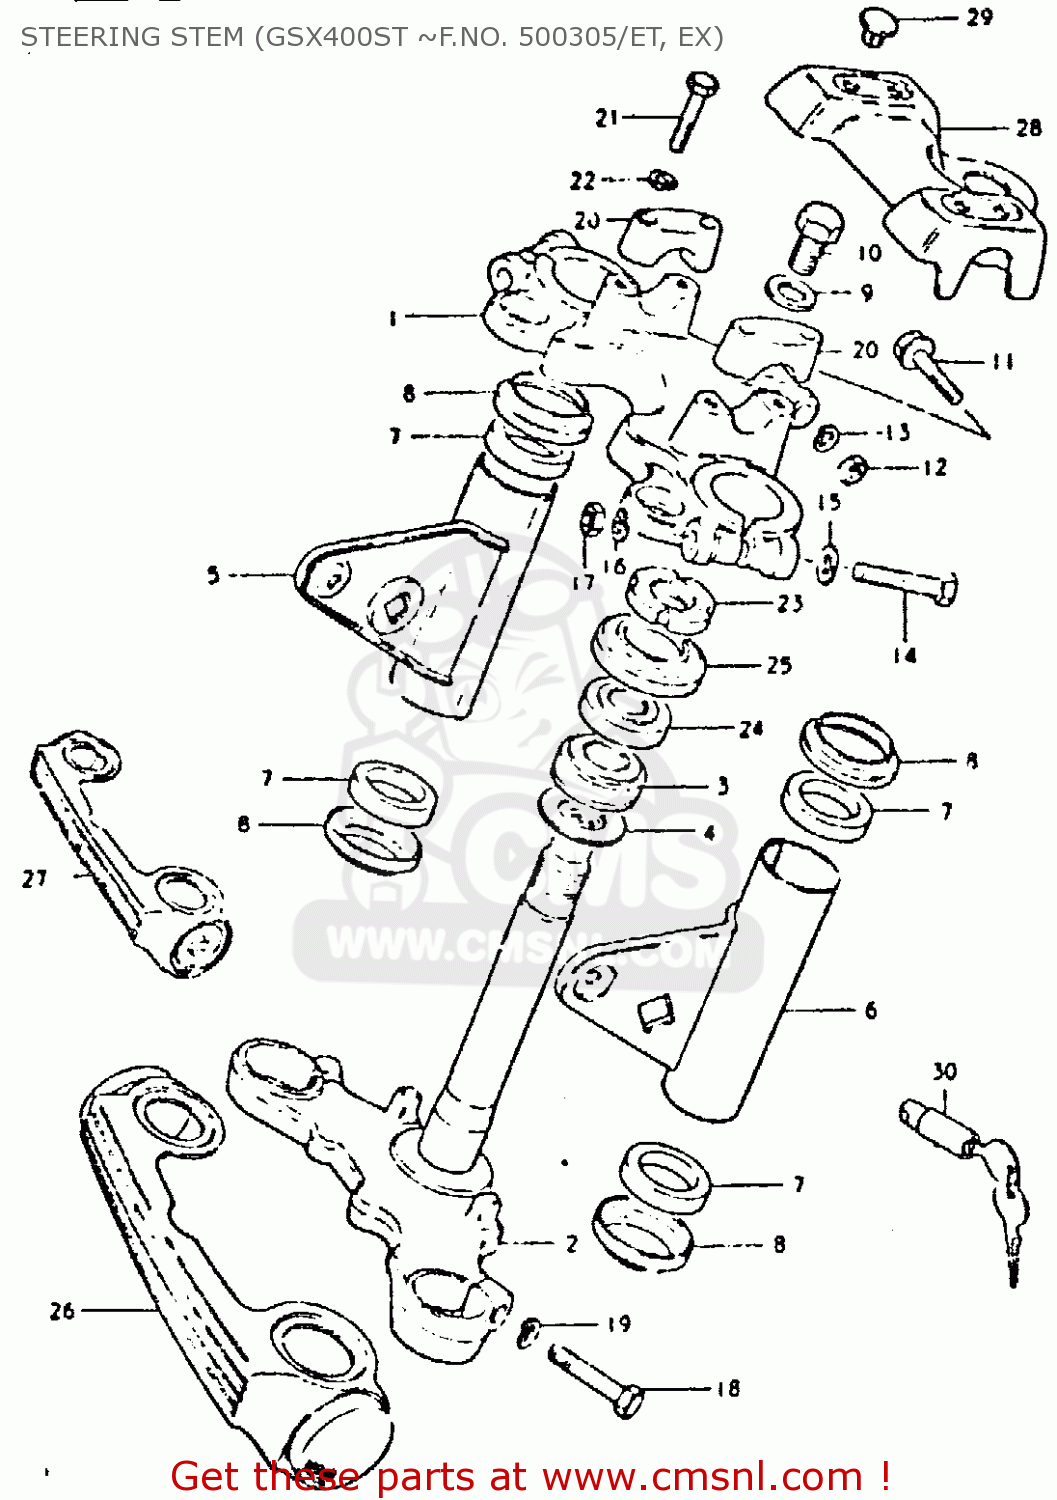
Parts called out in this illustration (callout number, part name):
1	HEAD,STEERING STEM
2	STEM,STEERING
3	BEARING
4	WASHER,THRUST
5	BRACKET,HEADLAMP,RIGHT
6	BRACKET,HEADLAMP,LEFT
7	CUSHION,HEADLAMP BRACKET
8	CAP,HEADLAMP BRACKET
9	WASHER
10	BOLT(12X20)
11	BOLT
12	NUT
13	LOCK WASHER
14	BOLT 10X55
15	WASHER
16	LOCK WASHER
17	NUT
18	BOLT 10X40
19	LOCK WASHER
20	HOLDER,HANDLE UPR
21	BOLT 8X35
22	WASHER,LOCK,8.
23	NUT,STEERING STEM(25X44X10)
24	TAPER,ROLLER BEARING
25	DUST SEAL,STEERING,UPPER
26	COVER,FR FORK
28	PAD,HANDLE
29	CAP(OD:19.5)
